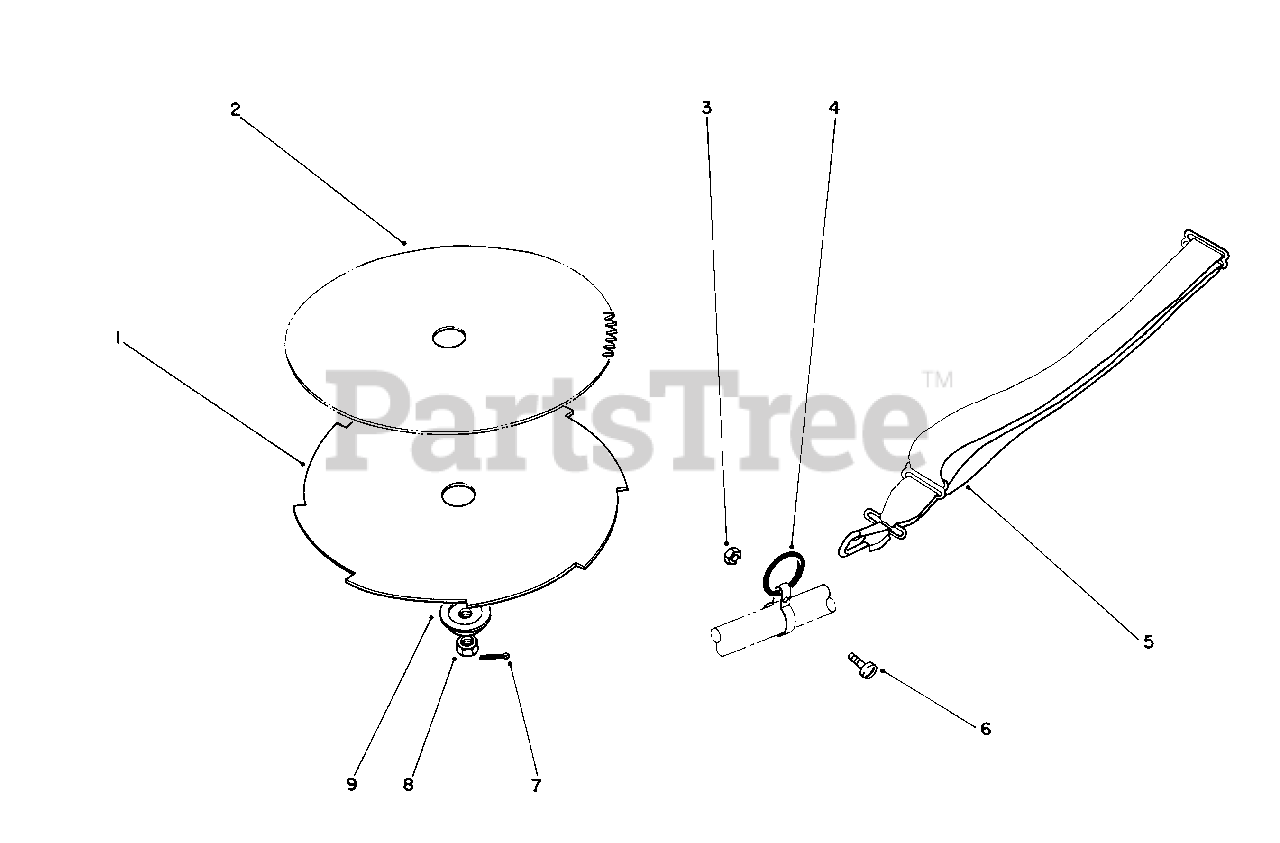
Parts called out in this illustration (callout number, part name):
1	8" Dia. Blade (8 Tooth)
2	8" Dia. Blade (80 Tooth)
3	Nut-Lock
4	Ring-Harness
5	Strap-Shoulder
7	Pin-Cotter
8	Nut L.H.
9	Adapter-Blade
